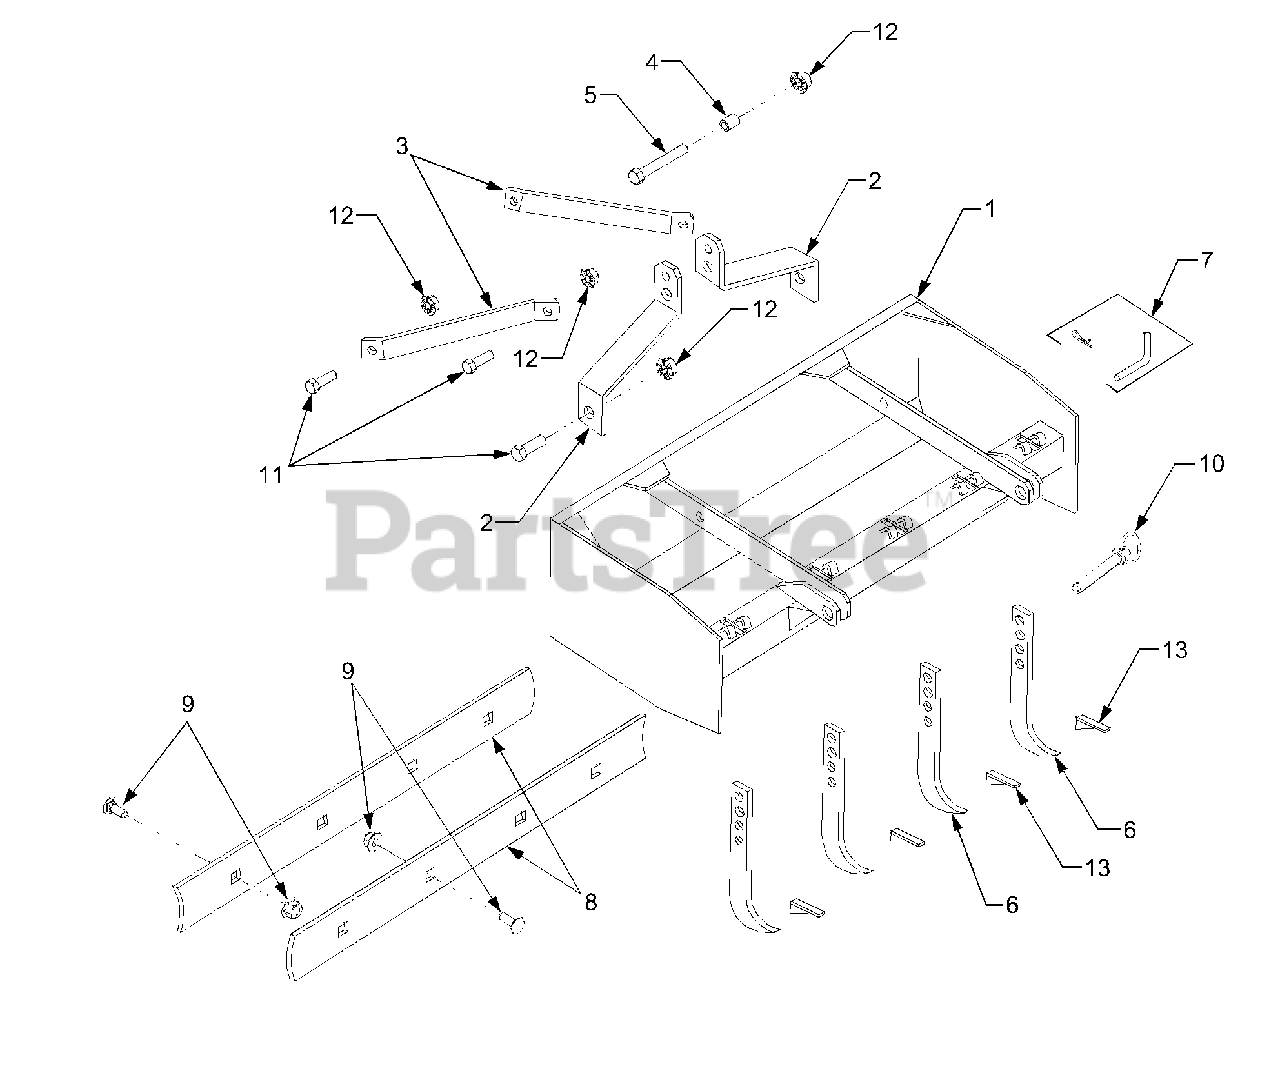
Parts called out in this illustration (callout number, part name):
2	Vertical Support
3	Horizontal Support
4	Inner Spacer
5	Bolt, 3/4 x 4.0
6	Scarifier Shanks
7	Bent Pin w/Cotter Pin
8	Scraper Blade
9	Plow Bolt w/Nut
11	Bolt, 3/4 x 1-3/4
12	Stover Nut, 3/4
13	Scarifier Tooth
